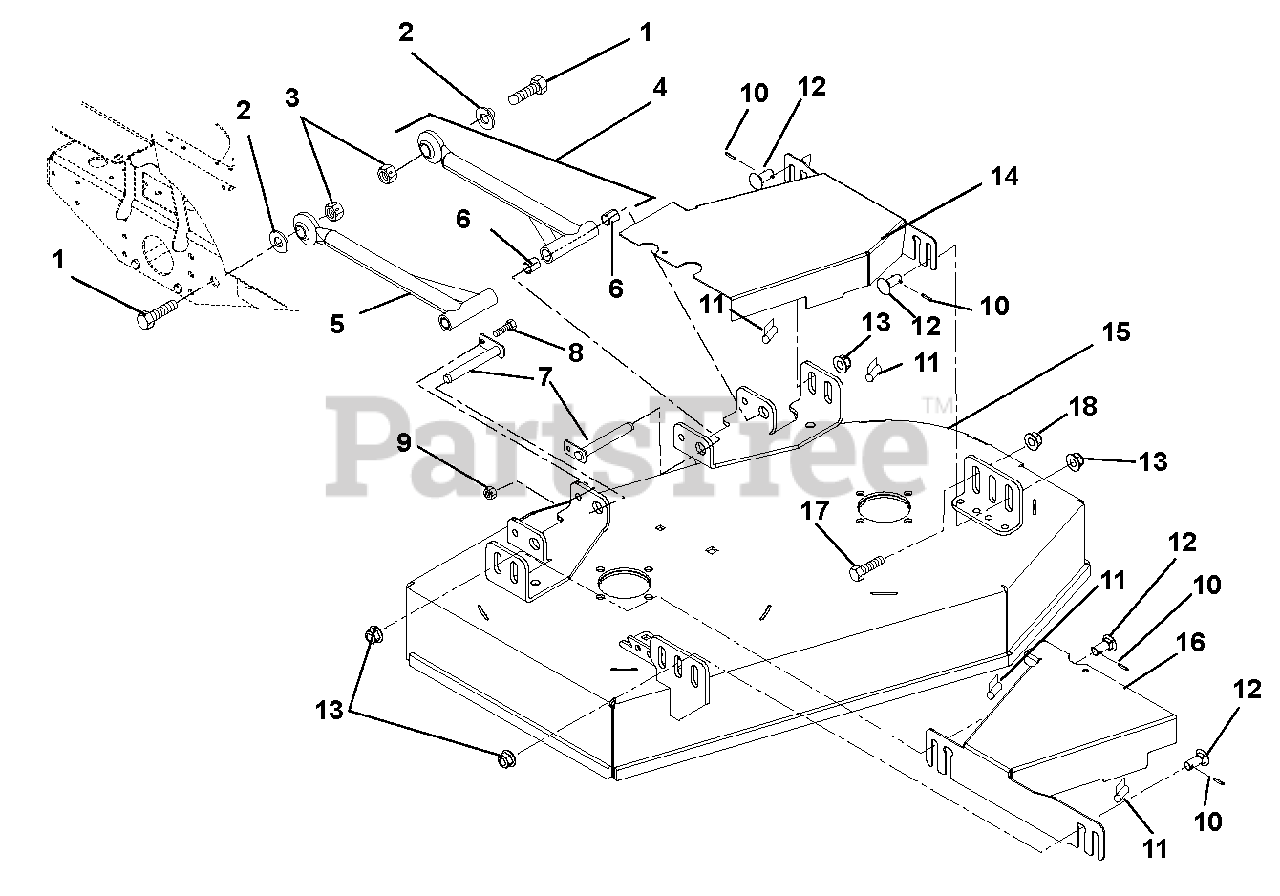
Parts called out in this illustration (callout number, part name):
1	Bolt, Hex .875-9 x 3.00
2	Bushing, Sleeve .875 x 1.25 x .531
3	Nut, Locking Center .875-9
4	Assembly, Mower Mounting (Includes Items 5 and 6)
5	Arm, Mower Mounting
6	Bearing, .75 x .875 x 1.00
7	Weldment, Mower Mounting Pin
8	Bolt, Hex .38-16 x 1.00
9	Nut, Nyloc Flange 3/8-16
10	Pin, Roll .125 x .75
11	Seal, Trim-LOK Bulk .06 Bubble
12	Bolt, Round Head Square Neck .50-13 x 1.25 SPL
13	Nut, Nyloc Flange .50-13
14	Weldment, Belt Guard 34" Left Hand
15	Weldment, 34" Mower Deck, Rear Discharge
16	Weldment, Belt Guard 34" Right Hand
17	Bolt, Round Head Square Neck .31-18 x .75 Grade 5 (991301)
18	Nut, Locking Nylon Flange .31-18 YZ (991301)
